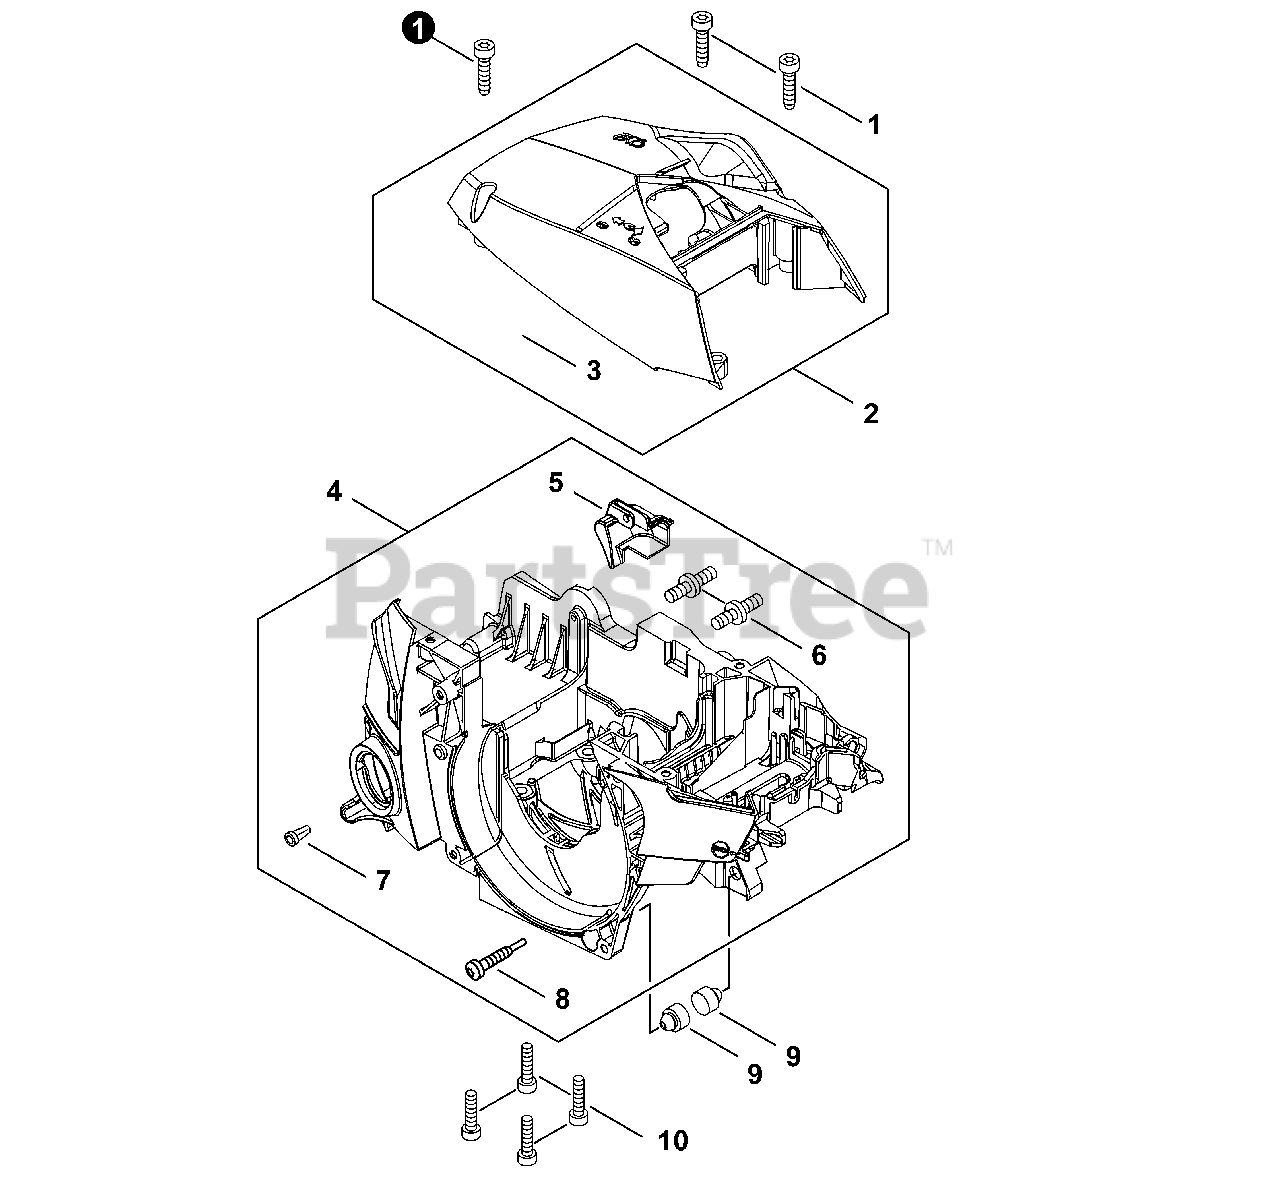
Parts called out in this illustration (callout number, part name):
1	BOLT, TORX 5×20
2	COVER, CYLINDER
3	LABEL, ECHO
4	HOUSING ASSY, ENGINE
5	DUCT, AIR
6	BOLT, STUD 8
7	VENT ASSY
9	CUSHION
10	BOLT 5×40
